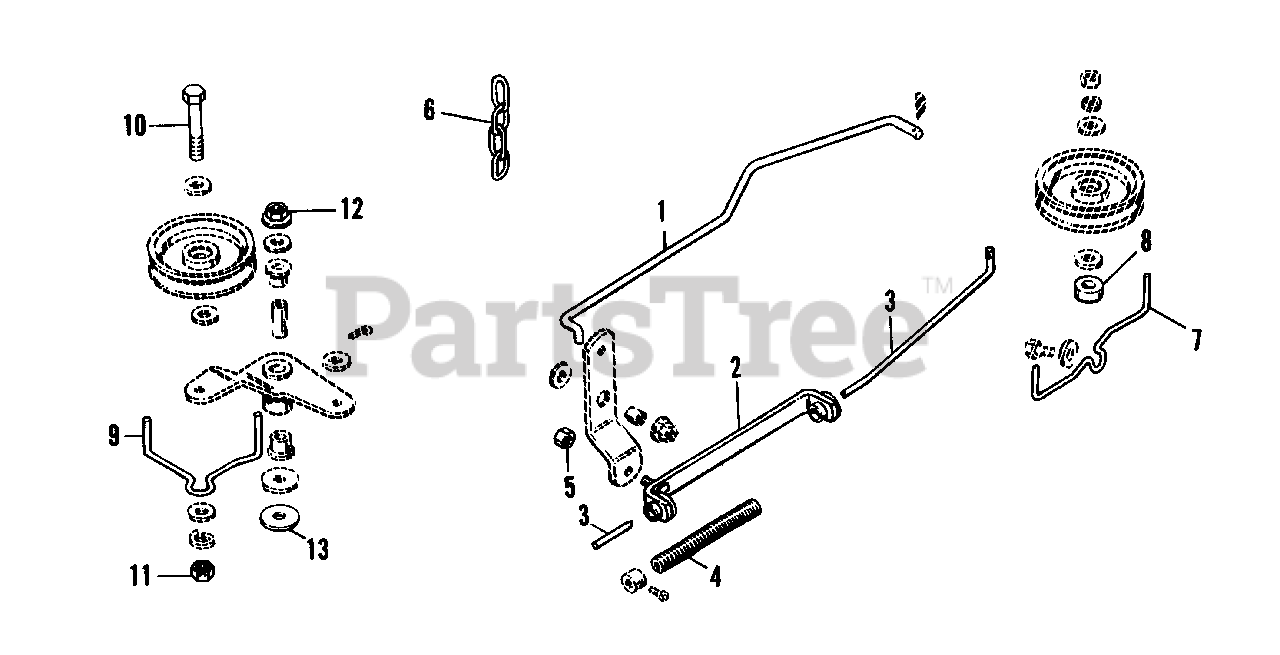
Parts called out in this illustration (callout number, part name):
1	ROD, P.T.O.
2	ROD GUIDE ASSY.
3	ROD, Clutch
5	LOCKNUT, Jam, 5/16-18
6	CHAIN, Lift
10	CAPSCREW, Hex Hd., 3/8-16 x 1-1/2
11	NUT, Jam, 3/8-16
12	LOCKNUT, Hex, Flange, 3/8-16
